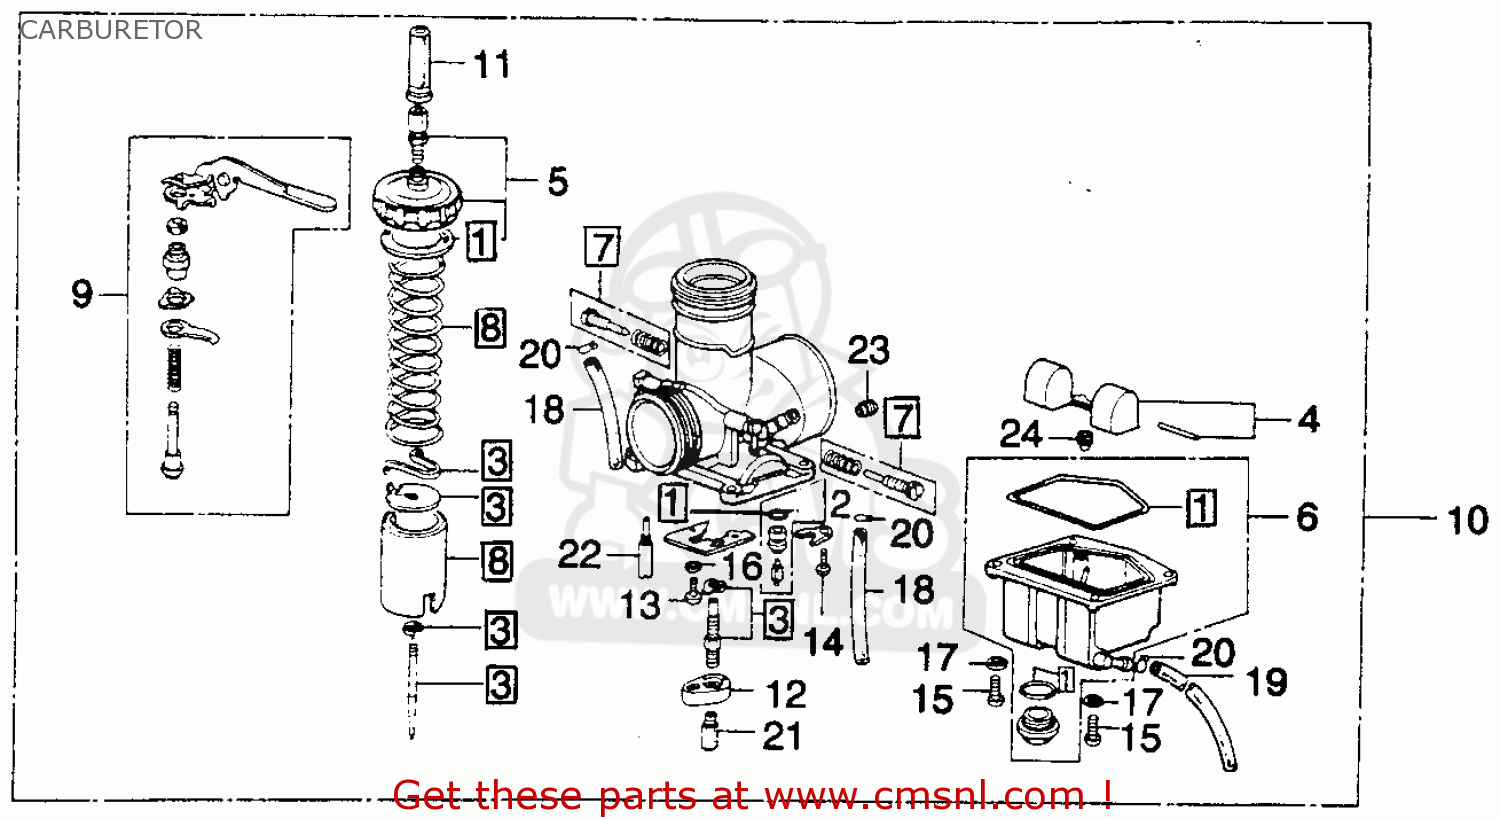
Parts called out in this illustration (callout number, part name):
1	GASKET SET
2	VALVE SET,FLOAT
3	NEEDLE SET, JET
4	FLOAT SET
5	TOP SET
6	CHAMBER SET,FLOAT
7	SCREW SET
8	VALXE SET,THROTTL
9	VALVE SET, STARTER
10	CARBU,MT250
11	CAP,RUBBER
12	JET HOLDER
13	SCREW,CROSS 3X6
14	SCREW,CROSS,4X10
15	SCREW,CROSS,4X14
16	SPG,WASHER3MM
17	WASHER,SPG.,4MM
18	BULK TUBE,F 35X3M
20	CLIP B7,TUBE
21	JET,MAIN#115
22	JET,SLOW#60
23	JET,AIR#160
24	AIR JET,PRIMARY
